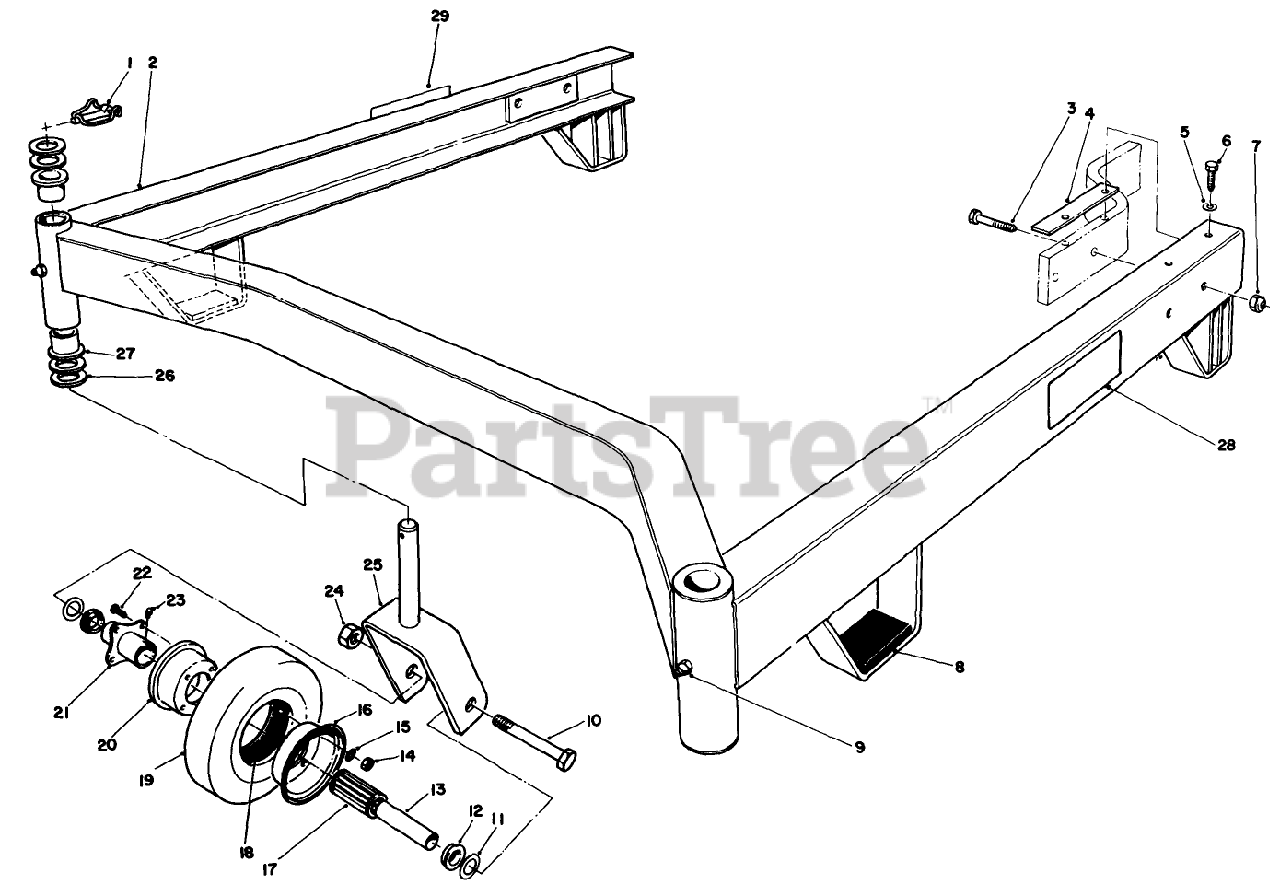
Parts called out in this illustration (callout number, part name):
1	PIN-LYNCH
3	SCREW-HH
4	SHIM-CARRIER
5	WASHER-FLAT
6	SCREW W/PATCH
7	NUT-LOCK, CONE
8	CUSHION-RUBBER
9	FITTING-GREASE
10	SCREW-HH
11	WASHER-FLAT
12	BEARING-OUTSIDE
13	SPANNER-TIRE
14	NUT-HEX
15	SCREW-HH
16	MALE WHEEL HALF
17	BEARING-ROLLER
18	TUBE-INNER (W/VALVE)
20	FEMALE WHEEL HALF
21	HUB-CENTER
22	WHEEL BOLT
23	FITTING-GREASE
24	NUT-HEX
26	WASHER-THRUST
28	DECAL-HOC, RH
29	DECAL-HOC, LH
